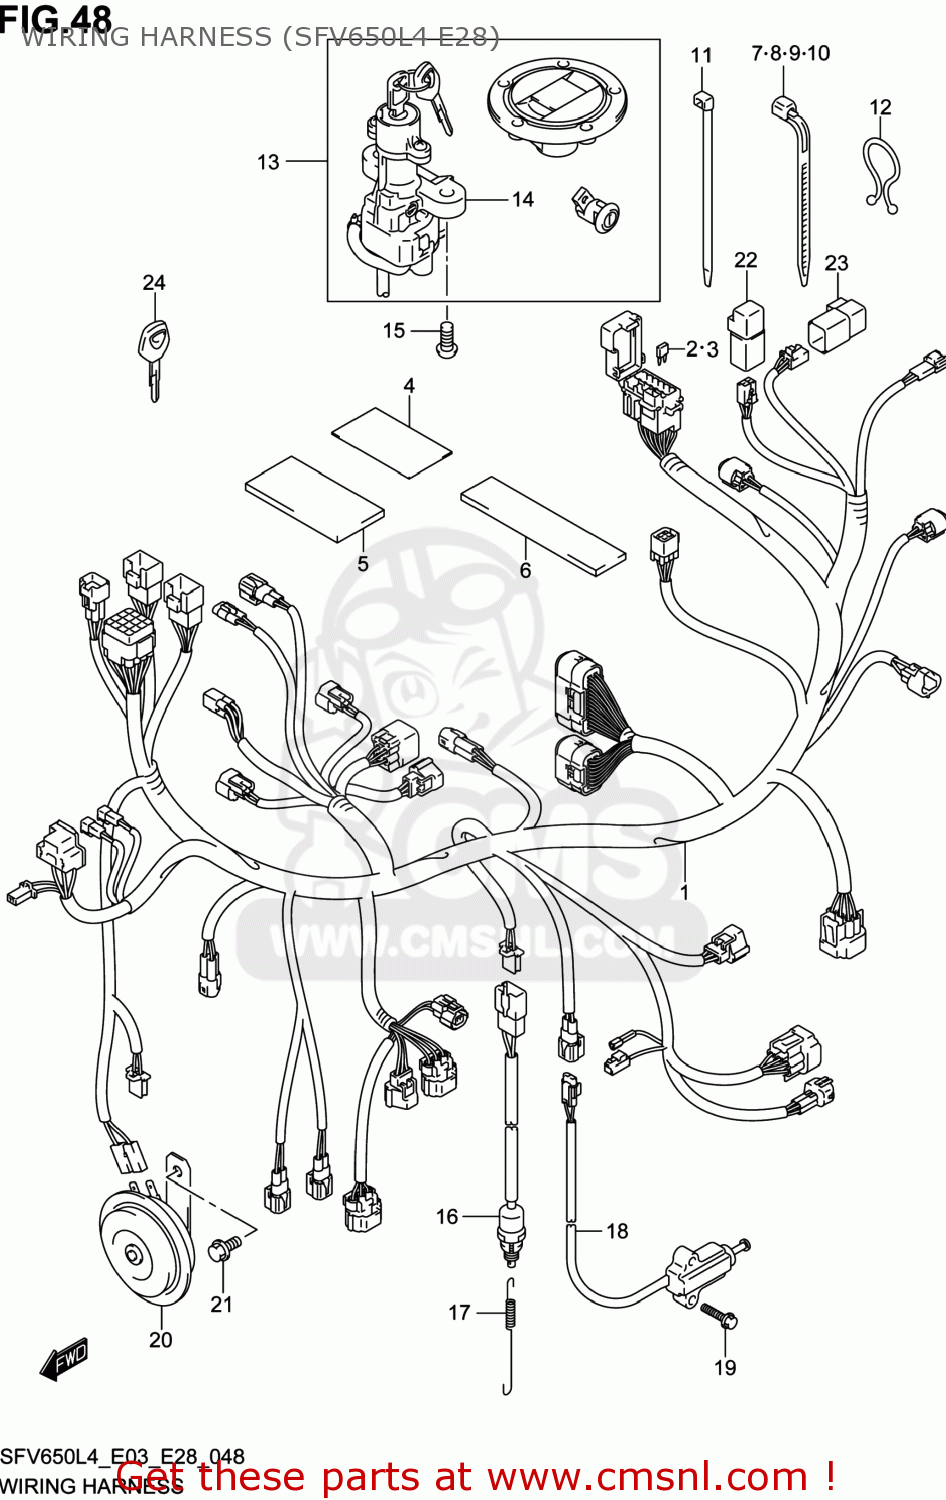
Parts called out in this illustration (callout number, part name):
1	HARNESS,WIRING
2	FUSE(10A)
3	FUSE(15A)
4	TAPE,WIRING HARNESS(28X50X0.13
5	PROTECTOR(30X60X3)
6	PROTECTOR
7	CLAMP(L:95)
8	CLAMP(L:125)
9	CLAMP(L:165)
10	CLAMP(L:190)
11	CLAMP(L:145)
12	CLIP(ID:11.5)
13	LOCK SET
14	LOCK ASSY,STEERING
15	BOLT(8X20)
16	SWITCH ASSY,STOP LAMP
17	SPRING
18	SWITCH ASSY,SIDE STAND
19	BOLT
20	HORN ASSY
21	BOLT
22	RELAY ASSY
23	RELAY ASSY
24	KEY,BLANK
